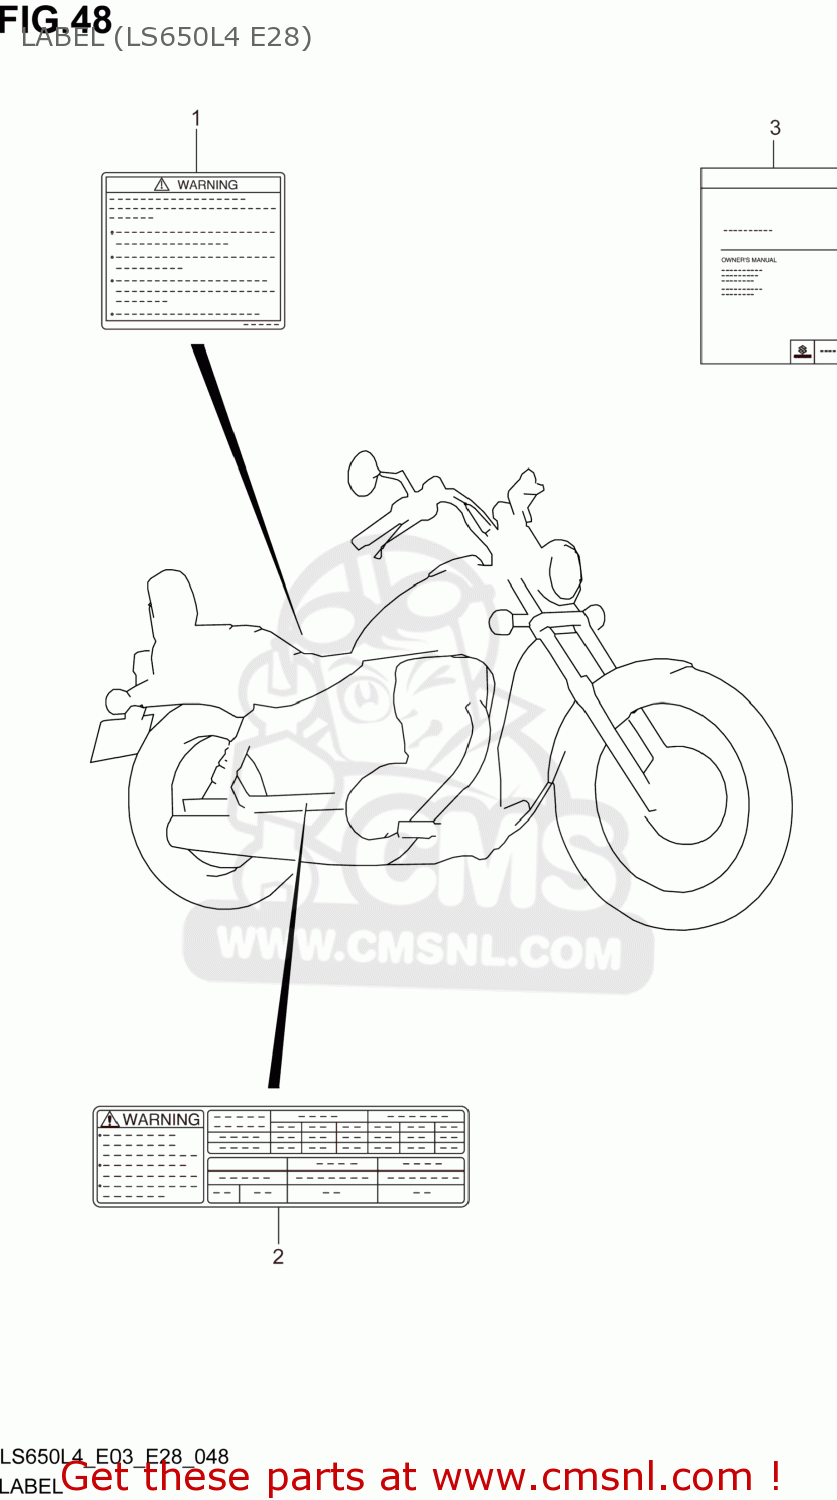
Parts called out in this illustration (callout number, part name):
1	LABEL,GENERAL WARNING
2	LABEL,TIRE INFORMATION
3	MANUAL,OWNER'S
